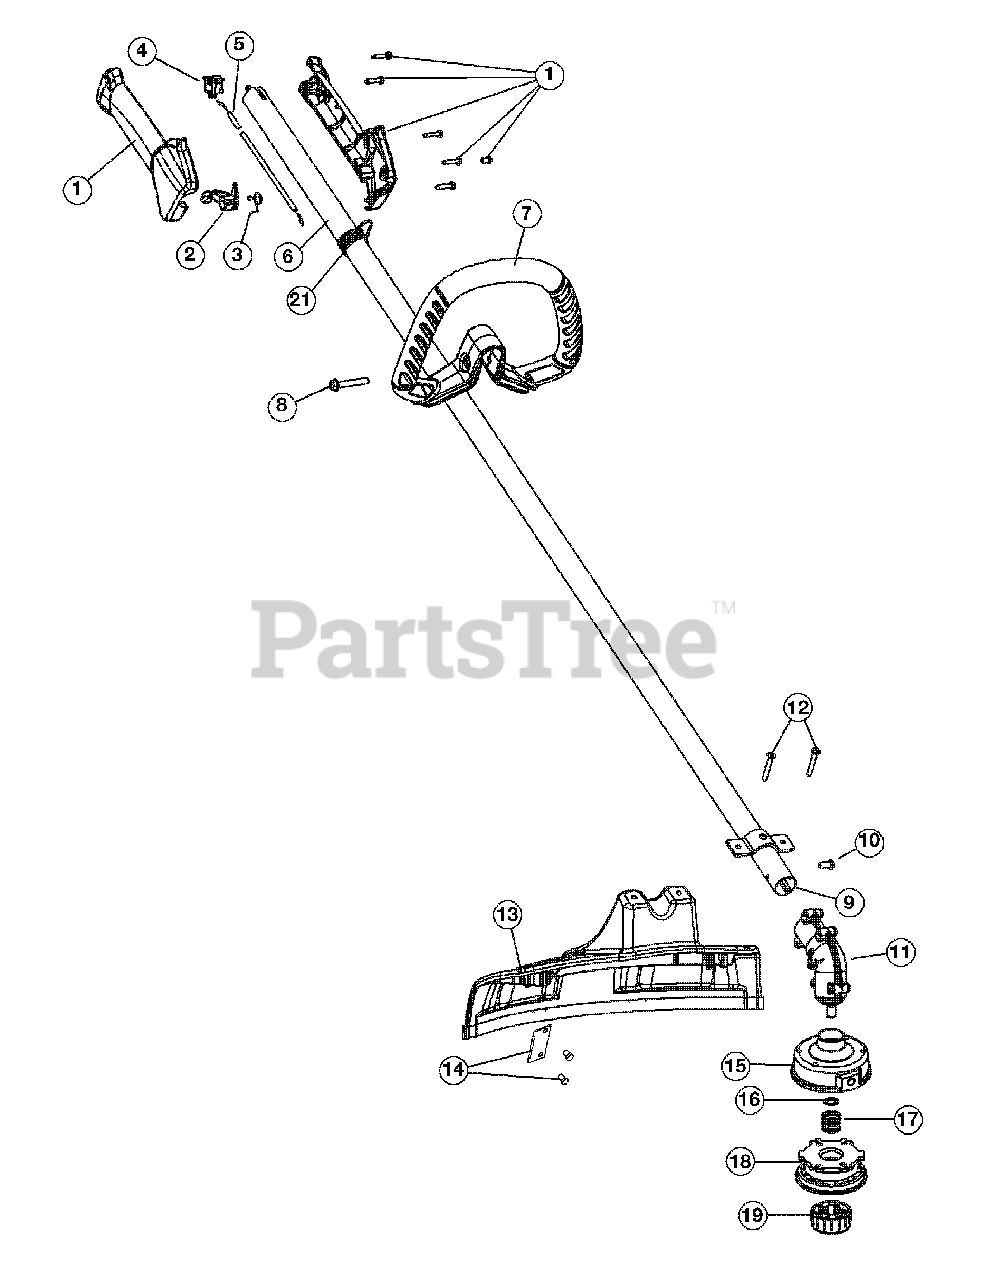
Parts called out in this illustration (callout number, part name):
1	Throttle Housing Assembly
2	Throttle Trigger
3	Throttle Trigger Spring
5	Throttle Cable Assembly
6	Drive Shaft Housing
7	D-Handle Assembly
9	Flexible Drive Shaft
10	Anti-Rotation Screw
11	Gearbox Assembly
12	Shield Mounting Screws
13	Shield Assembly
14	Blade Assembly
15	Out Spool Assembly
18	Inner Reel
19	Bump Know Assembly
